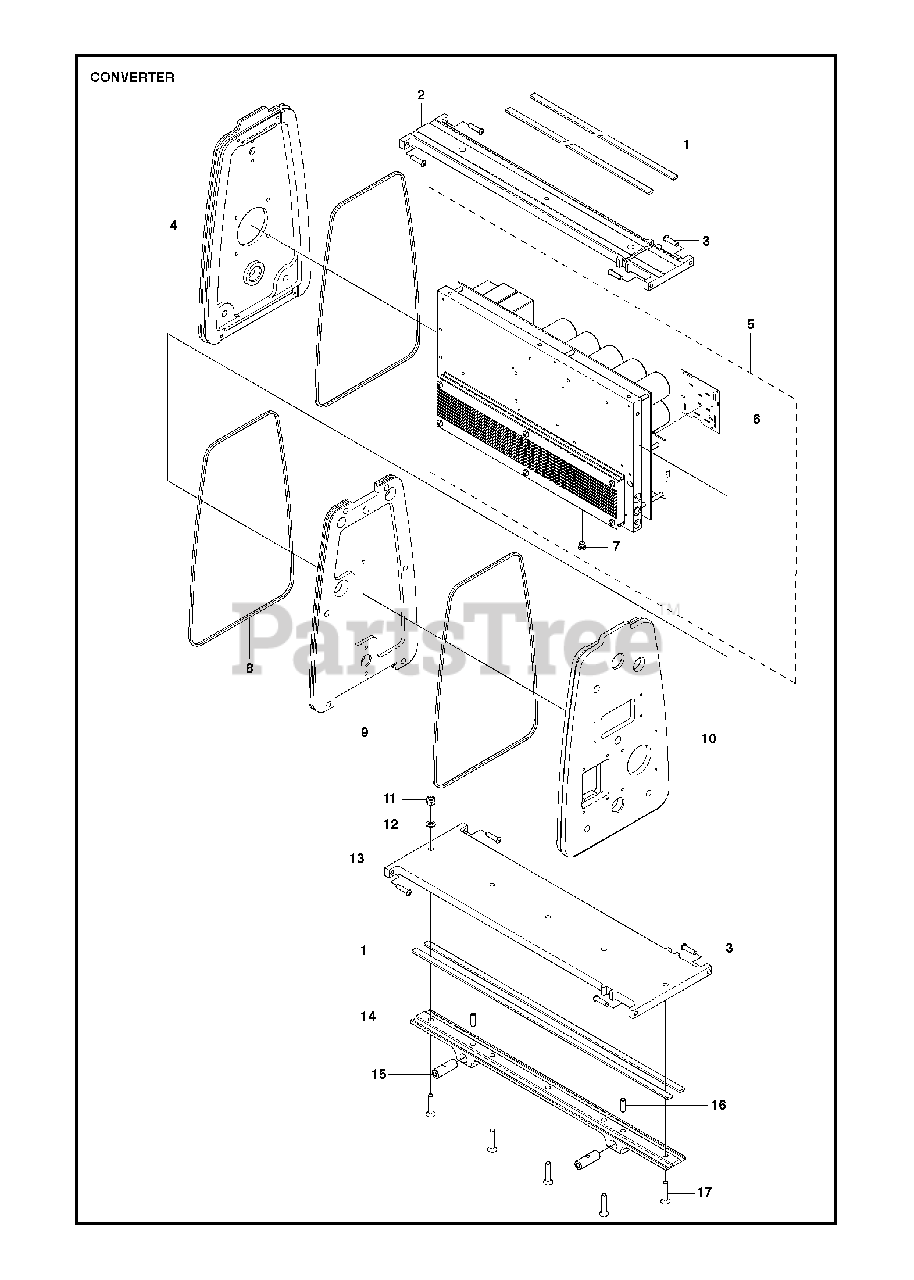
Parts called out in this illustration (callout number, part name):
2	SUPPORT PLATE200-280V
5	PRINTED CIRCUIT ASSY400-480V incl. 6 - 7
5	PRINTED CIRCUIT ASSY200-280V incl. 6 - 7
6	PRINTED CIRCUIT ASSY400-480V
6	PRINTED CIRCUIT ASSY200-280V
11	HEXAGON LOCKING NUT
